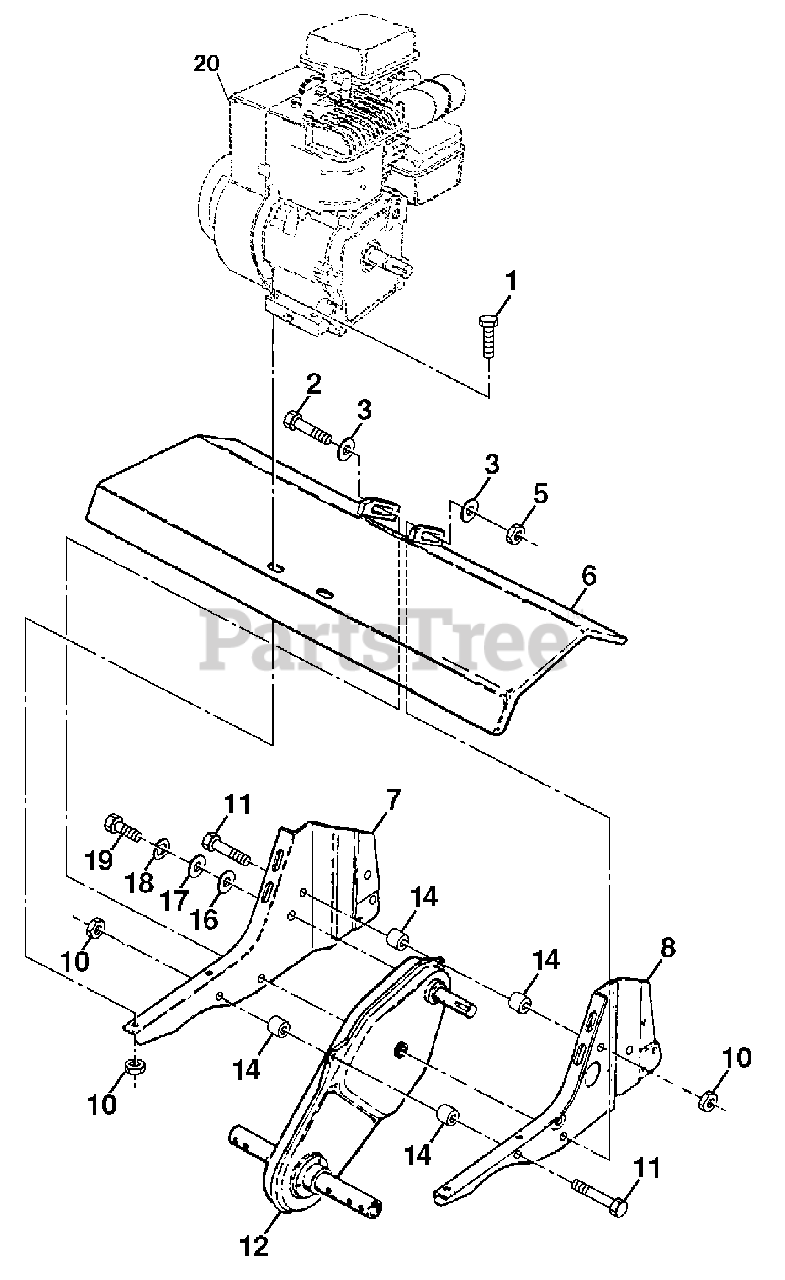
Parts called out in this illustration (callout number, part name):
1	Bolt, Hex 5/16-18 x 1-1/2 Gr. 2
2	Bolt, Hex, Fin 3/8-16 x 3-1/4
3	Washer 13/32 x 13/16 x 11
5	Locknut, Hex, w/washer 3/8-16
7	Bracket, Engine, R.H.
8	Bracket, Engine, L.H.
10	Nut, Lock Hex Flange
11	Bolt, Hex 5/16-18 x 2-3/4
12	Transmission
14	Spacer, Split
16	Washer 9/32 x 7/8 x 12 Ga.
17	Washer 9/32 x 1-1/4 x 16 Ga.
18	Washer, Lock 1/4
19	Bolt, Hex 1/4-28 x 3/4 Gr. 5
